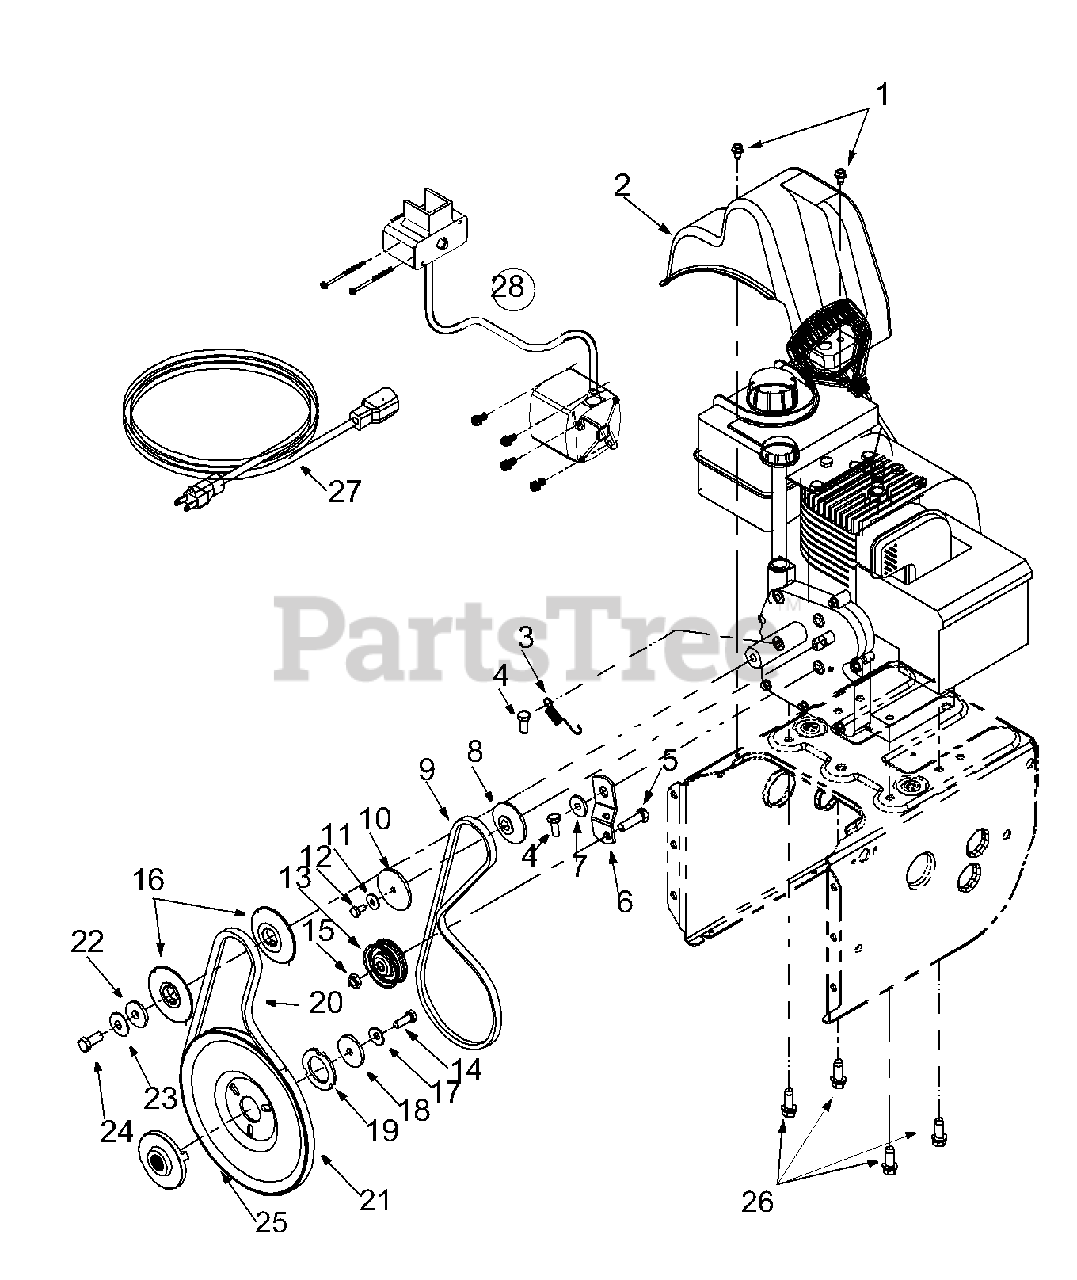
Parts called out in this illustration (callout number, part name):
1	Hex Washer Screw 1/4-20 x.5
2	Belt Cover
3	Extension Spring
4	Hex Screw 5/16-24 x .75
5	Hex Cap Screw 3/8-16 x 1.25
8	Pulley Half
9	V-Belt
10	Pulley Half
11	Bell Washer
12	Hex Cap Screw 1/4-28 x .50
13	Flat Idler
14	Lock Cap Screw 5/16-24
15	Lock Jam Nut 3/8-16
16	Pulley Half
17	Bell Washer
18	Flat Washer
19	Washer
20	Belt
21	Auger Pulley
22	Flat Washer
23	Bell Washer
24	Hex Cap Screw 3/8-24
25	Pulley
26	Hex Washer Screw 3/8-16 x 1.0
27	Extension Cord
28	Electric Start Kit
